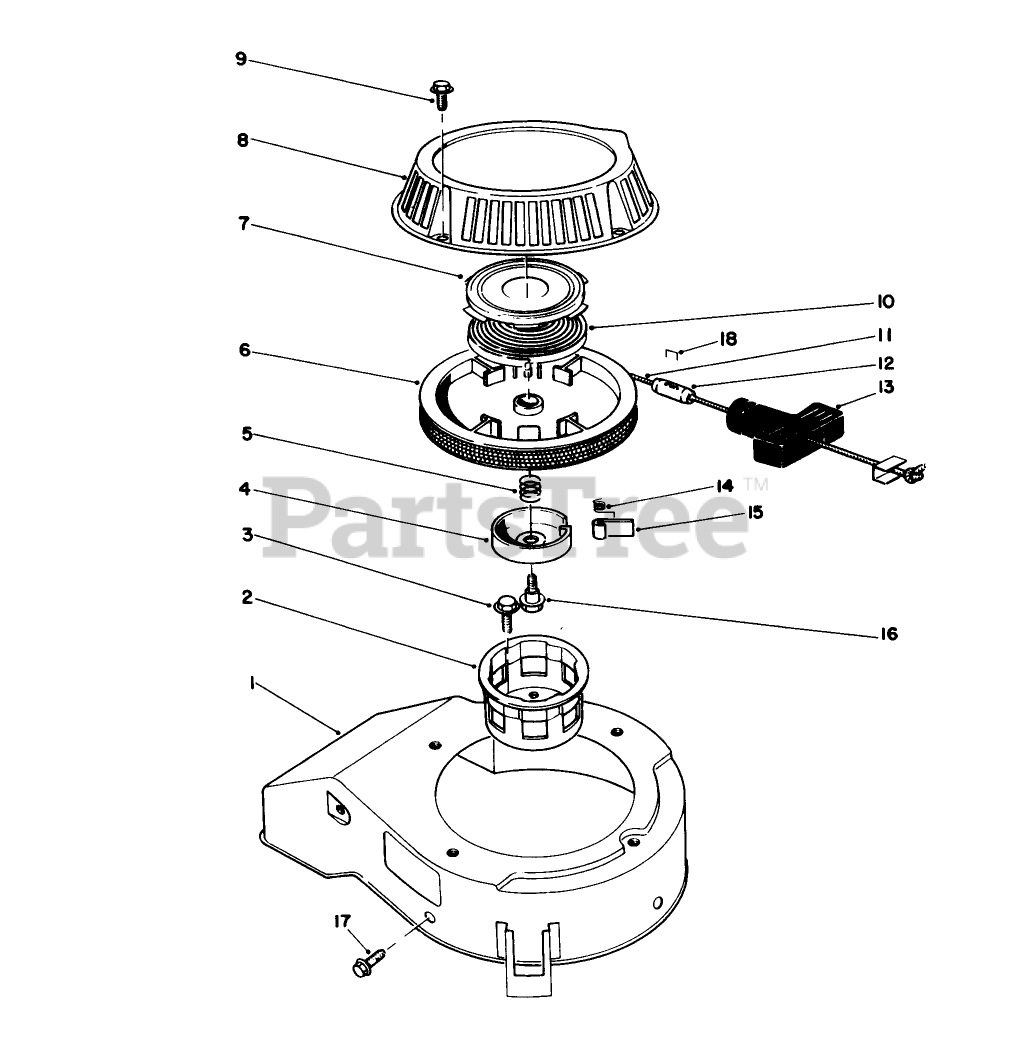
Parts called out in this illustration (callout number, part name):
1	COVER
2	CUP - STARTER
4	RETAINER
5	SPRING
7	Retainer Cup-Recoil Spring
9	SCREW-HHF
10	Spring-Recoil
11	ROPE-STARTER
13	HANDLE-RECOIL
14	SPRING
18	Staple
